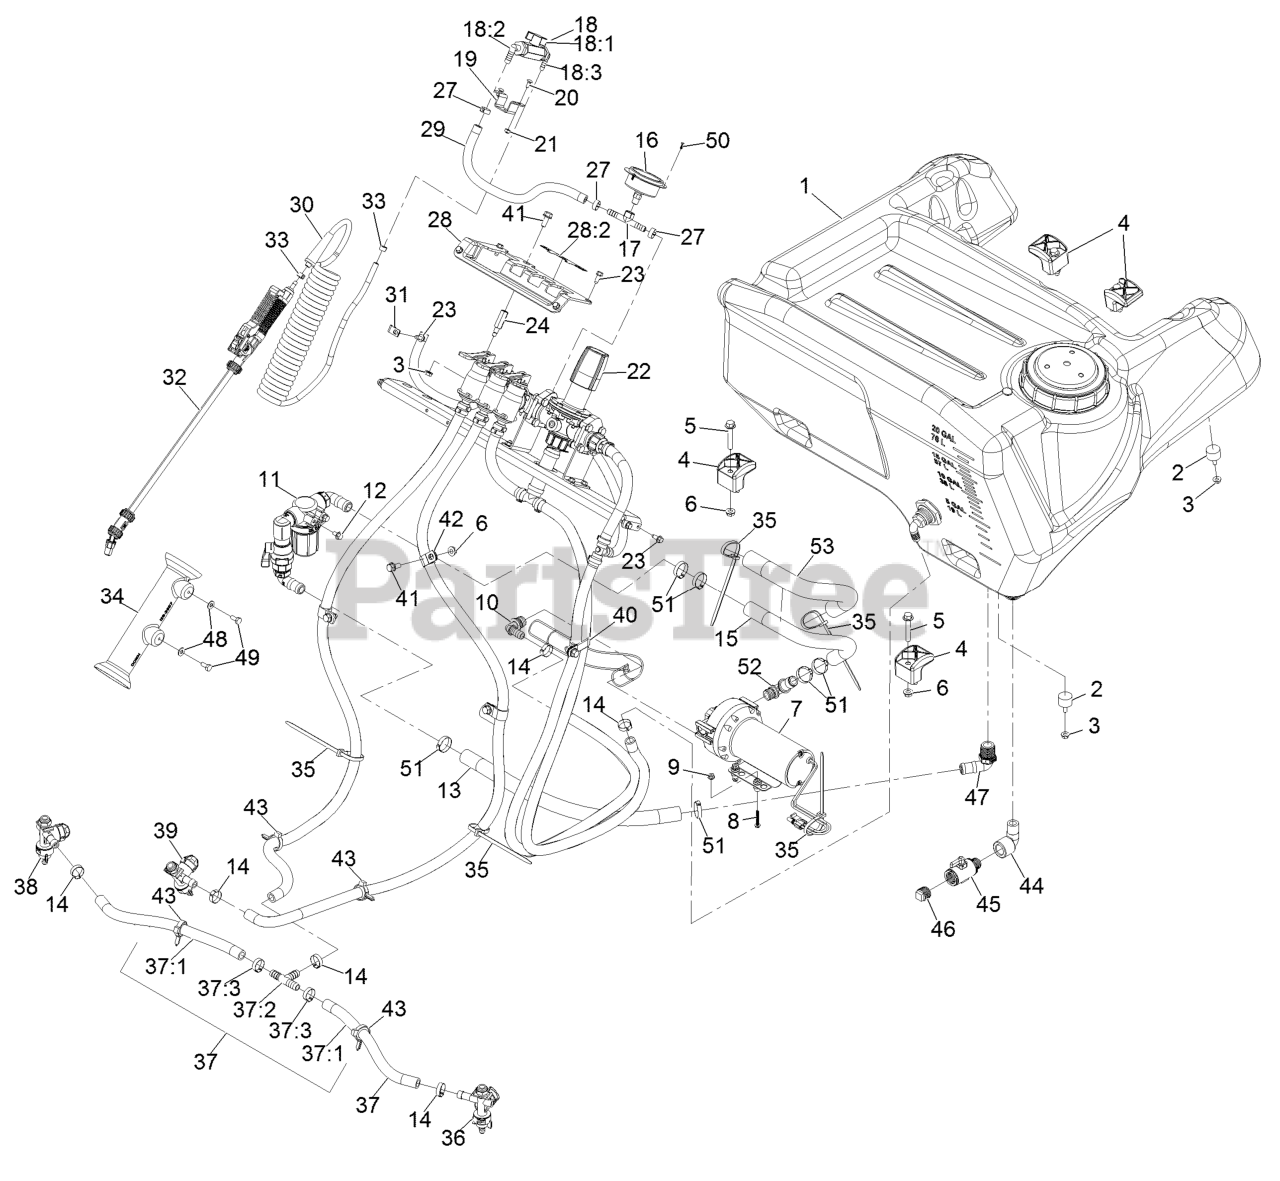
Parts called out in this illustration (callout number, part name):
1	TANK-SPRAYER
5	SCREW-HHF
7	PUMP-DIAPHRAGM, 3.8 GPM
8	SCREW-SHWH
10	FITTING-ELBOW, BARBED
11	STRAINER ASM
12	SCREW-HHF
13	HOSE-WATER
15	HOSE-WATER
16	GAUGE-PRESSURE
17	FITTING-TEE
18	Wand Control ASM
18:1	VALVE-BALL
18:2	FITTING-ELBOW-90
18:3	FITTING-ELBOW-90
19	BRACKET-VALVE
20	BOLT-CARR
21	NUT-LOCK, NI
22	CONTROL VALVE MANIFOLD AS
23	SCREW-HWH
24	SPACER-MOUNT, MANIFOLD
28	COVER-CONTROLS
28:2	DECAL-CONTROL, LEVER
29	HOSE-WATER, 3/8 PVC RED
30	HOSE-COILED
31	CLAMP-R
32	SPRAY WAND ASM
34	HOLDER-WAND
35	TIE-PLASTIC
36	LEFT NOZZLE SUB ASM
37	HOSE ASM
37:1	HOSE-WATER
37:2	FITTING-TEE
38	RIGHT NOZZLE SUB ASM
39	CENTER NOZZLE SUB ASM
41	SCREW-HHF
42	CLIP-LOOM
43	CLAMP-HOSE
44	ELBOW-90 DEG
45	MICROVALVE
47	ELBOW-HOSEBARB
48	WASHER-FLAT
49	SCREW-HH
50	SCREW-TAP
52	FITTING-ELBOW
53	SLEEVE-CORRUGATED, SPLIT
